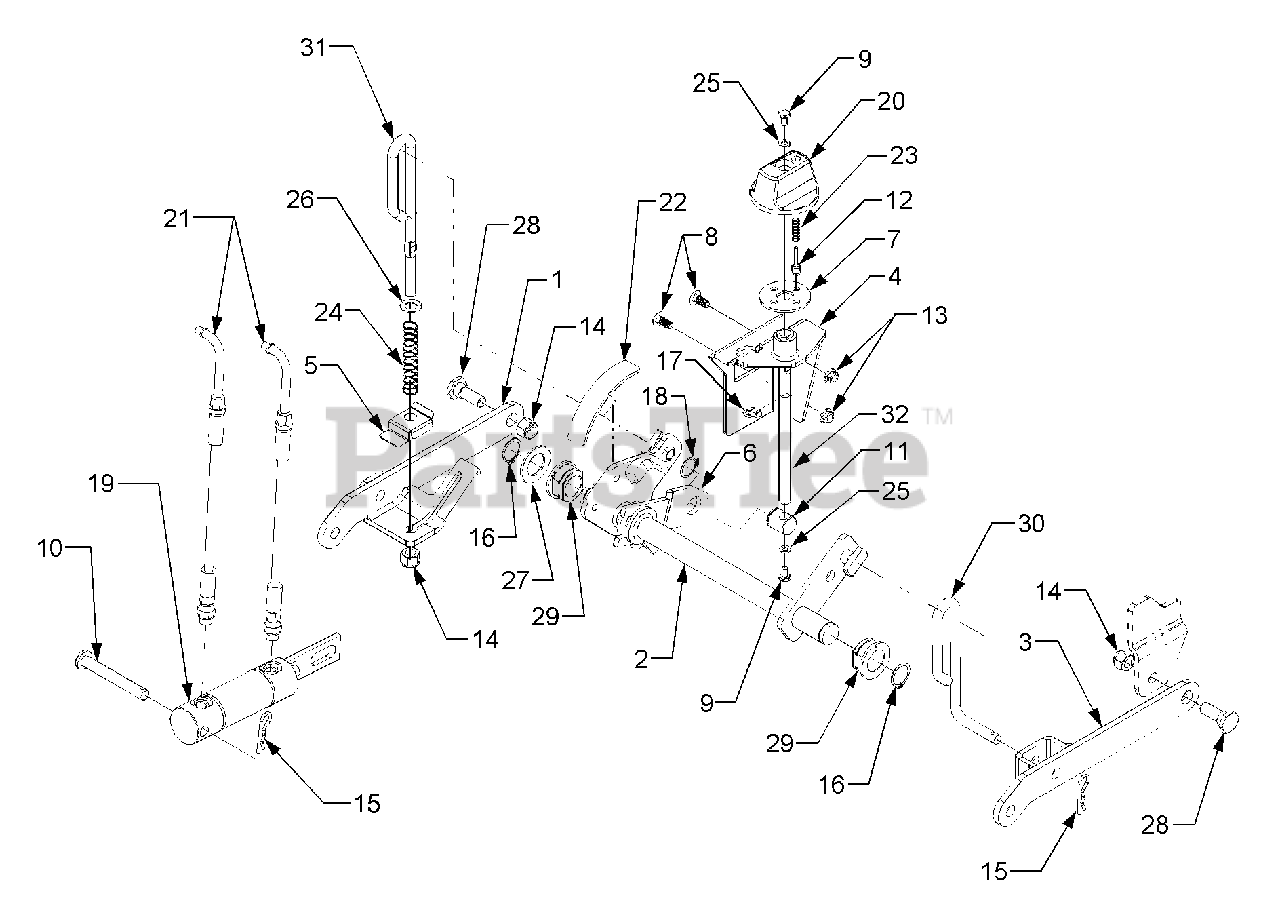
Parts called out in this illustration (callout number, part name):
1	Link, LH Lift
4	Bracket, Downstop
5	Stop Bracket, Lift Rod
6	Arm, Downstop
7	Disk, Detent
8	Bolt, Carriage, 3/8-16 x .75
9	Screw, Hex Cap, 1/4-20 x .5 GR5
10	Pin, Clevis, .5 x 3.75
11	Ferrule, Adjustment
12	Pin, Detent Plunger
13	Nut, Flange Lock, 3/8-16 GR5
14	Nut, Hex Lock, 1/2-13
15	Pin, Internal Cotter
16	Snap Ring, 1.0 Dia. Shaft
17	Ring, 'E' Retaining, .5 Dia.
18	Snap Ring, .875 Dia. Shaft
19	Cylinder, Center Lift
20	Knob
21	Hose, Lift
22	Indicator, Lift Position
23	Spring, Compression
24	Spring, Compression
25	Washer, Flat, .281 x .5 x .063
26	Washer, Flat, .536 x .93 x .050
27	Washer. Flat, 1.0 x 1.7 x .10
28	Shoulder Screw
29	Bearing, Flange w/Flats
30	Rod, RH Lift
31	Rod, LH Lift
32	Screw, Adjustment
